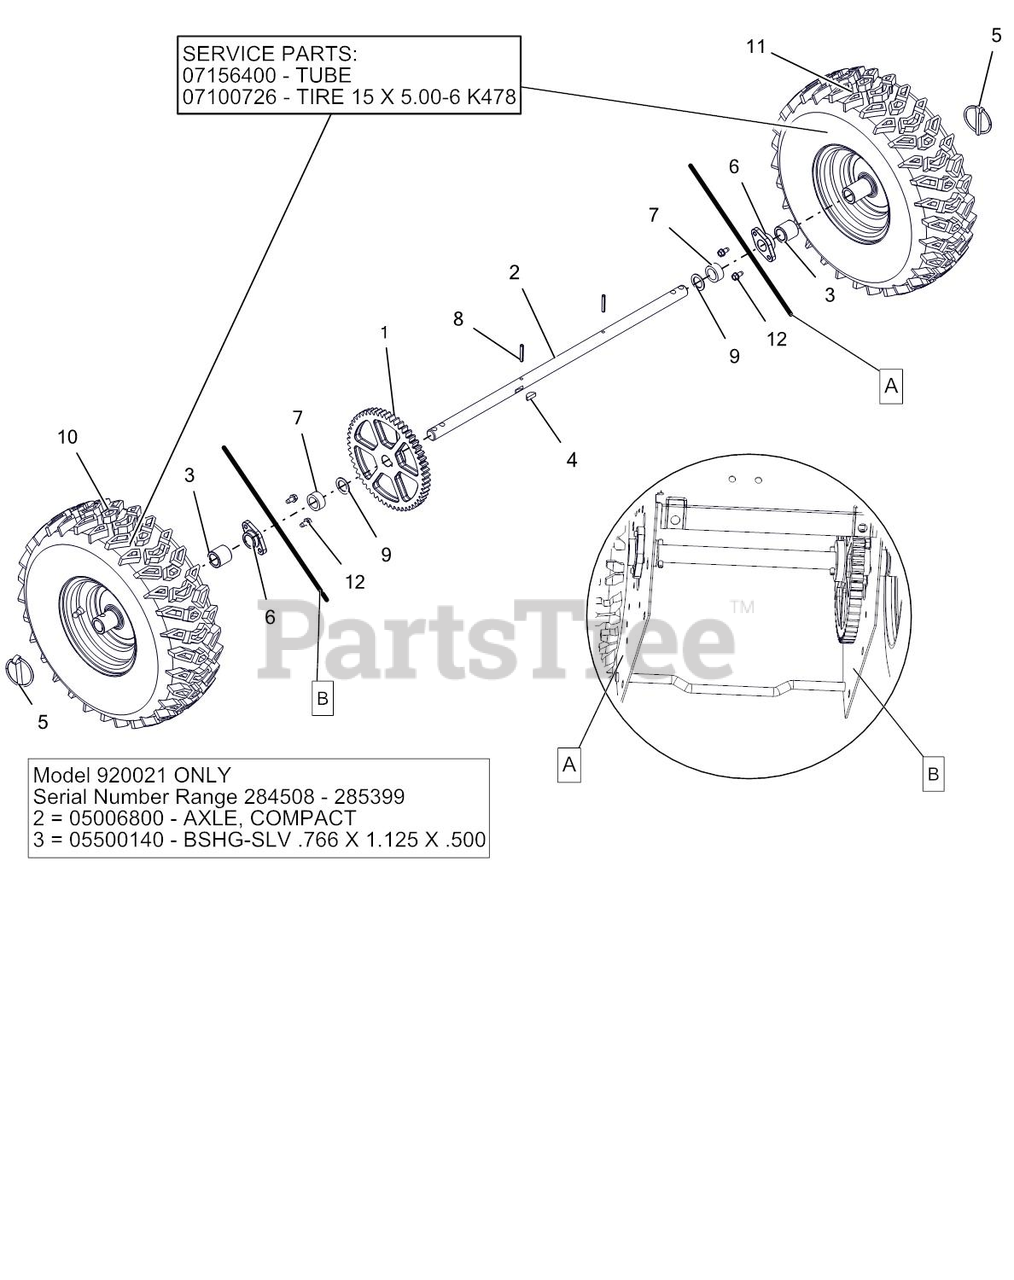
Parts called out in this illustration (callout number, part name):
1	SPUR GEAR, 54T .75ID X 6.75PD
2	AXLE, COMPACT 920,XXX 15" TIRE
2	AXLE, COMPACT
3	BSHG-SLV .766 X 1.125 X .500
3	BSHG-SLV .75X1.12X1.062 NYL BK
4	KEY-WDRF .25X.750X.313 SAE91
5	PIN-LOK .31X1.75
6	BSHG .75X1.125X.65
7	BSHG-SLV .766 X 1.125 X .500
8	PIN-ROLL .188X1.25
9	WSHR-FL-STL.754X1.125X.062YWZC
10	TIRE/WHEEL,RH 15X5.00-6 PIN T2
11	TIRE/WHEEL,LH 15X5.00-6 PIN T2
12	SCR-TAP .25-20X.50 HWH TR YWZ
13	TUBE 15 X 5.00-6
14	TIRE, 15X5.00-6 K478
